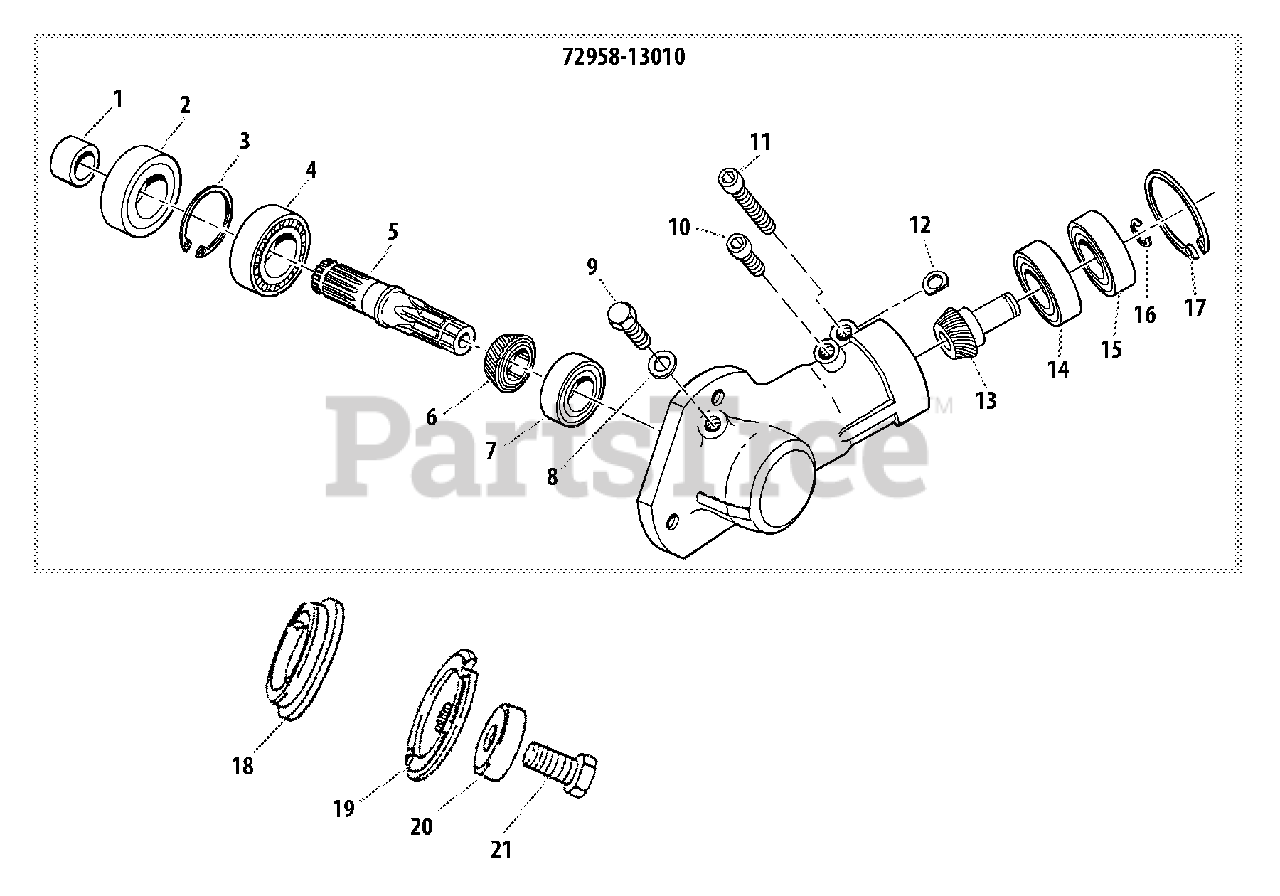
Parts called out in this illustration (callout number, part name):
1	COLLAR
2	SEAL, OIL
3	RING, RETAINING - 28
4	BEARING, BALL - 6001
5	GEAR - SHAFT
6	GEAR - BEVEL
7	BEARING, BALL - 608DDU
8	WASHER - 6
9	BOLT - 6X10
10	SCREW - 5X16
11	SCREW - 5X25
12	SHIM
13	GEAR - SHAFT
14	BEARING, BALL - 609
15	BEARING, BALL - 609ZZ
16	RING, RETAINING
17	RING, RETAINING - 24
18	HOLDER - A
19	HOLDER (B)
20	GUARD
21	BOLT - 8 -- LEFT HAND
72958-13010	GEAR CASE ASSY
